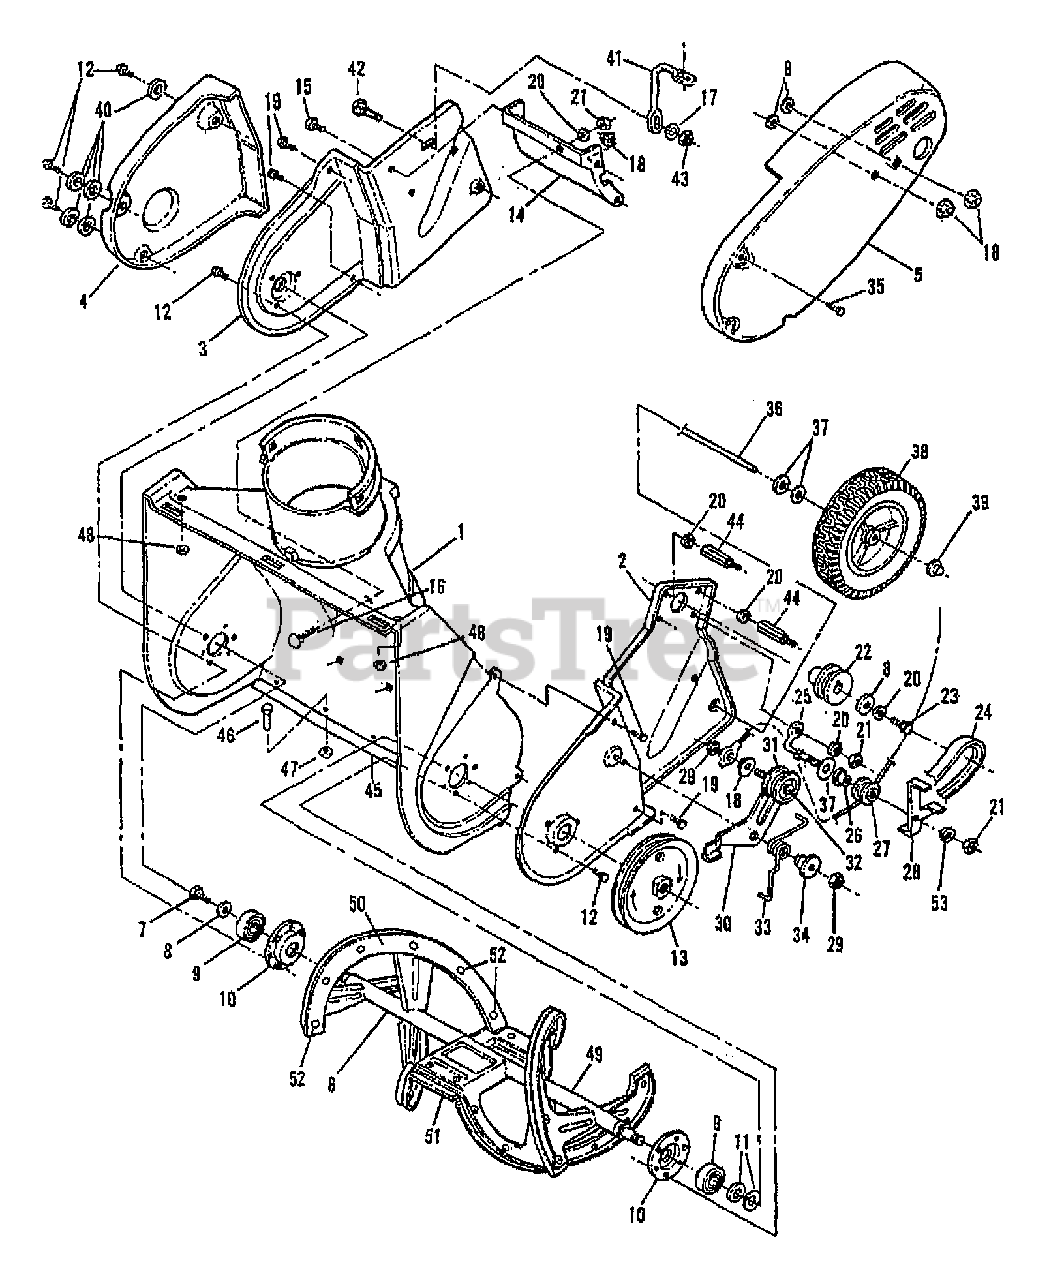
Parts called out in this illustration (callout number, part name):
1	ASSM-AUGER HOUSING
2	ASSM-END FRAME
3	FRAME-END RIGHT
4	COVER-SIDE
5	GUARD-BELT DRIVE
6	ASSM-AUGER
7	SCR-HH 5/16-18X.625
8	WASHER-FLAT 5/16
9	BEARING-BALL
10	RETAINER-BEARING
11	WASHER-SHIM 3/4
12	SCR-TORX HD #10-24X.5 STH
13	PULLEY
14	BRACE-ENGINE
15	SCR-HH 1/4-20X.375 STH
16	SCR-CARR 5/16-18X.75
17	WASHER-LOCK 1/4
18	NUT-HFLK 5/16-18
19	SCR-HH 1/4-15X1.0 STH
20	WASHER-LK 5/16
21	NUT-HEX 5/16-18
22	PULLEY-ENGINE
23	SCR-HH 5/16-24X.75
24	BELT-V
25	GUIDE-CABLE
26	BUSHING-FLANGE
27	PULLEY-NYLON
28	GUIDE-BELT
29	NUT-CTR LK 5/16-18
30	BRKT-IDLER PIVOT
31	PULLEY-IDLER SINGLE FLANGE
32	SCR-HH 5/16-18X.75 GR5
33	SPRING-IDLER TORSION
34	BUSHING-PIVOT
35	SCR-HH #10-16X.75 STH
36	AXLE-WHEEL 3/8
37	WASHER-FLAT 3/8
38	WHEEL-7 X 1.50
39	NUT-PUSH 3/8
40	WASHER-FLAT #10
41	SUPPORT-FUEL TANK
42	SCR-CARR 1/4-20X.625
43	NUT-NYLOCK 1/4-20
44	SPACER-HEX 2.69" LG
45	BLADE-SPACER
46	SCR-MACH 1/4-20X.5
47	NUT-NYLOCK 1/4-20
48	NUT-CTR LK 1/4-20
49	STRUCTURE-AUGER
50	SHOE-FLITE
51	SHOE-CENTER FLITE
52	SCR-HH #10-24X.5
53	WASHER-LK 5/16 EXT TOOTH
